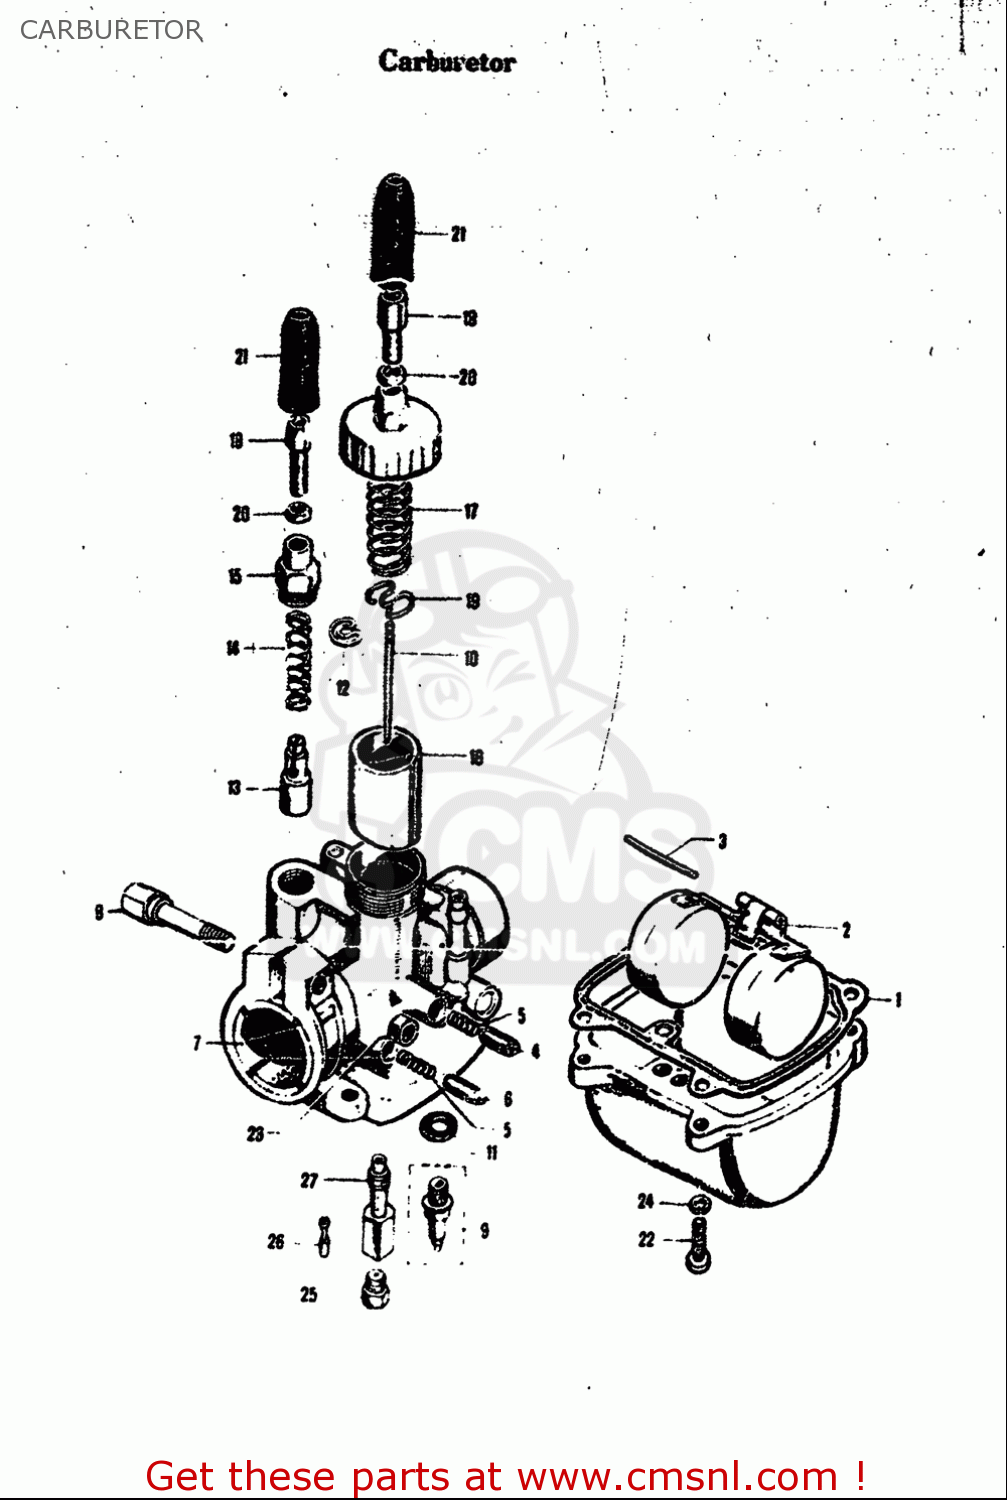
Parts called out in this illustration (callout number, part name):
1	GASKET,FLOAT CHAMBER (NAS)
3	PIN,FLOAT
4	SCREW,THROTTLE STOP
5	SPRING
6	SCREW,PILOT AIR
9	VALVE ASSY,NEEDLE
10	NEEDLE,JET
11	GASKET,NEEDLE VALVE (NAS)
12	CLIP
13	PLUNGER,STARTER
14	SPRING
17	SPRING,THROTTLE VALVE
18	ADJUSTER,CABLE
19	PLATE
20	NUT
24	WASHER,LOCK
25	JET,MAIN
